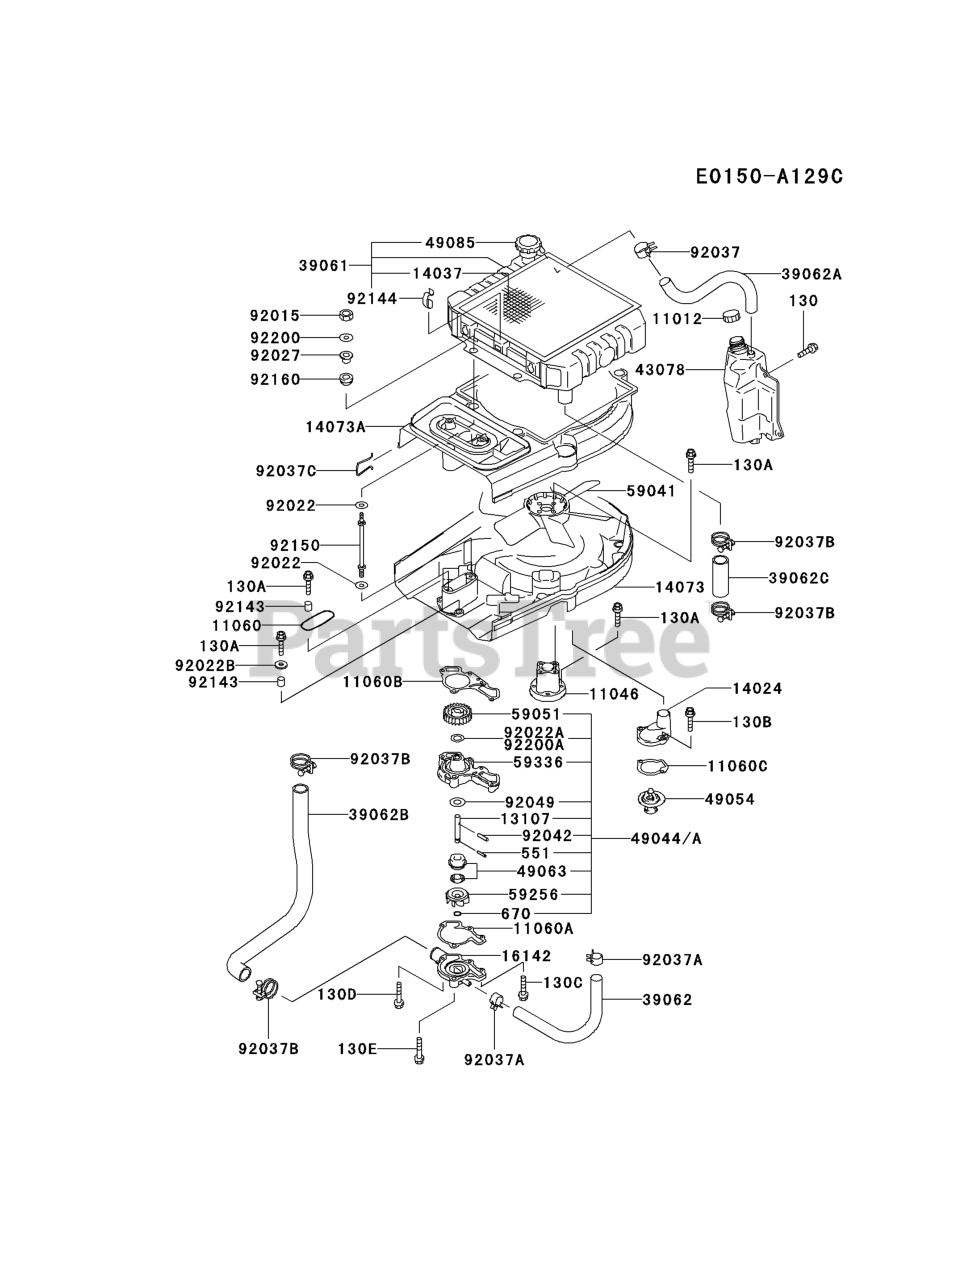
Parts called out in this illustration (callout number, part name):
130	BOLT-FLANGED,6X14
130A	BOLT-FLANGED,6X20
130B	BOLT-FLANGED,6X20
130C	BOLT-FLANGED,6X45
130D	BOLT-FLANGED,6X80
130E	BOLT-FLANGED,8X75
551	PIN-DOWEL,3X14
670	O RING,7MM
92200	WASHER,6.5 X 18 X 2.0
